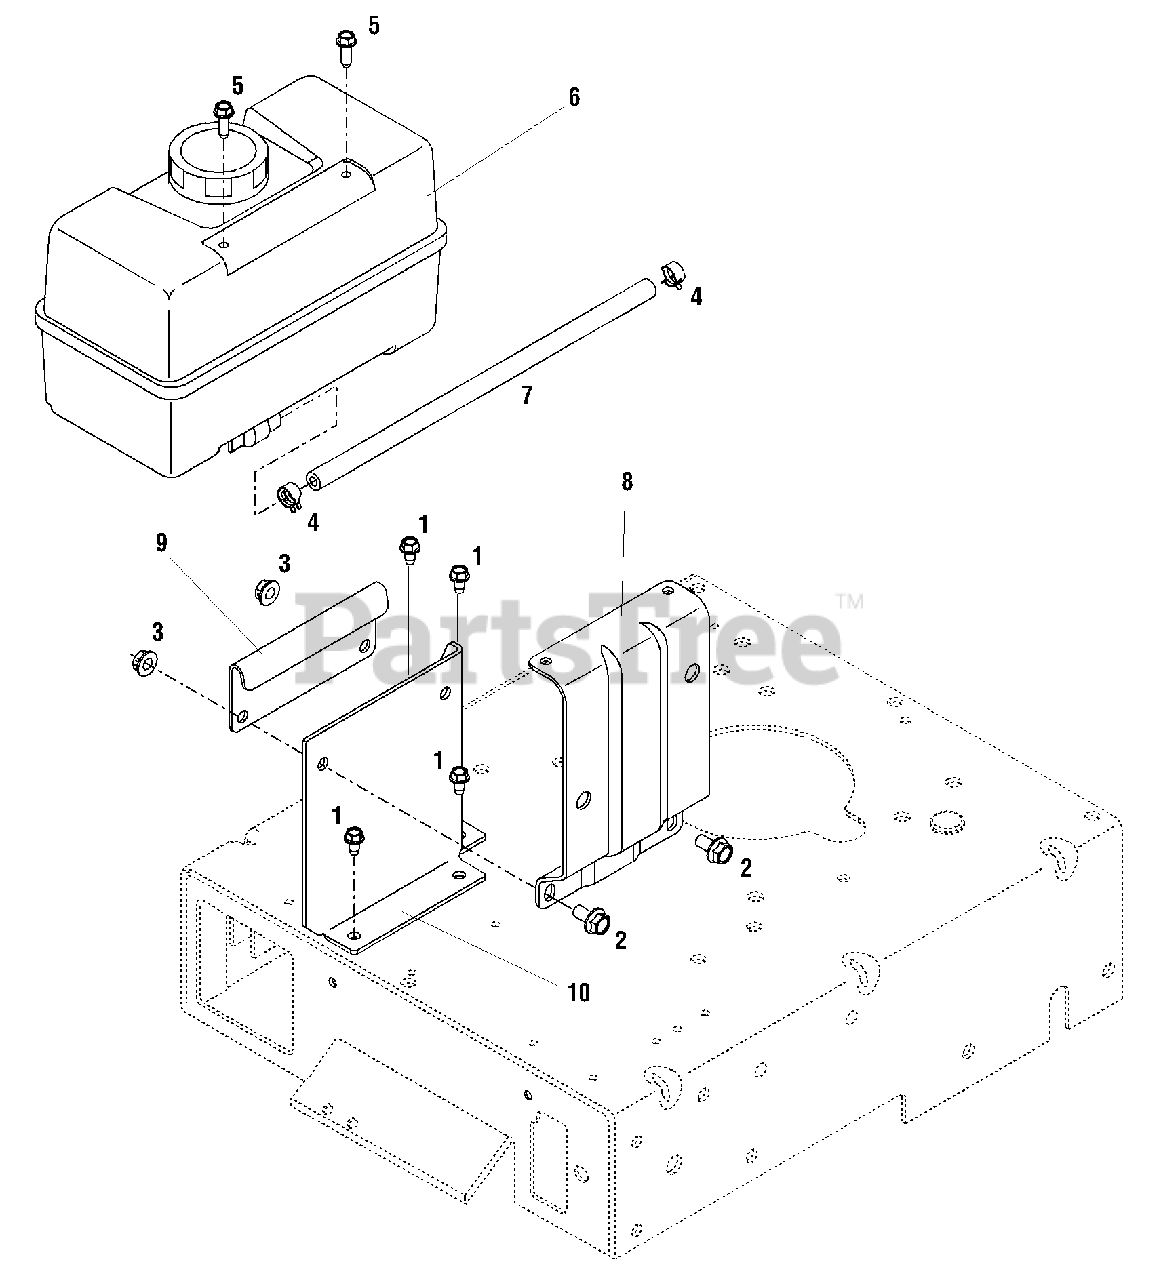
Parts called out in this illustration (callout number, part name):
1	Self-tapping Screw, 1/4-20 x 1/2
2	Hex Flange Screw, 5/16-18 x 5/8
3	Flange Locknut, 5/16-18
4	Hose Clamp
5	Screw, K80 x 3.59
6	Fuel Tank, 1 gal.
7	Fuel Line, 12"
